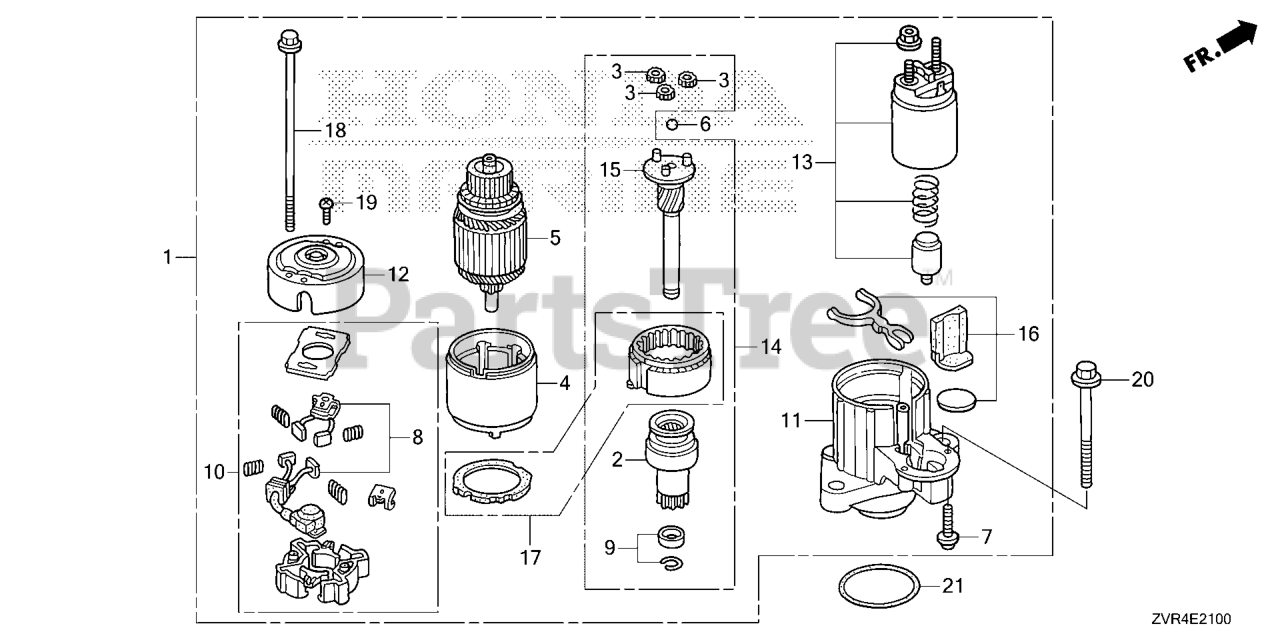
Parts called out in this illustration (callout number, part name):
1	STARTER MOTOR ASSY.
2	CLUTCH, OVERRUNNING
3	GEAR ASSY., PLANETARY
6	BALL, STEEL
7	SCREW, PAN (6X22)
9	STOPPER SET, SLEEVE
10	HOLDER, BRUSH
11	BRACKET, FR.
12	BRACKET, RR.
13	SWITCH ASSY., MAGNET
14	SHAFT ASSY., CLUTCH
15	SHAFT ASSY., GEAR
17	GEAR ASSY. (INNER)
18	BOLT A, THROUGH
19	SCREW, PAN (5X8)
20	BOLT, FLANGE (10X90)
21	O-RING (59.4X3.1)
